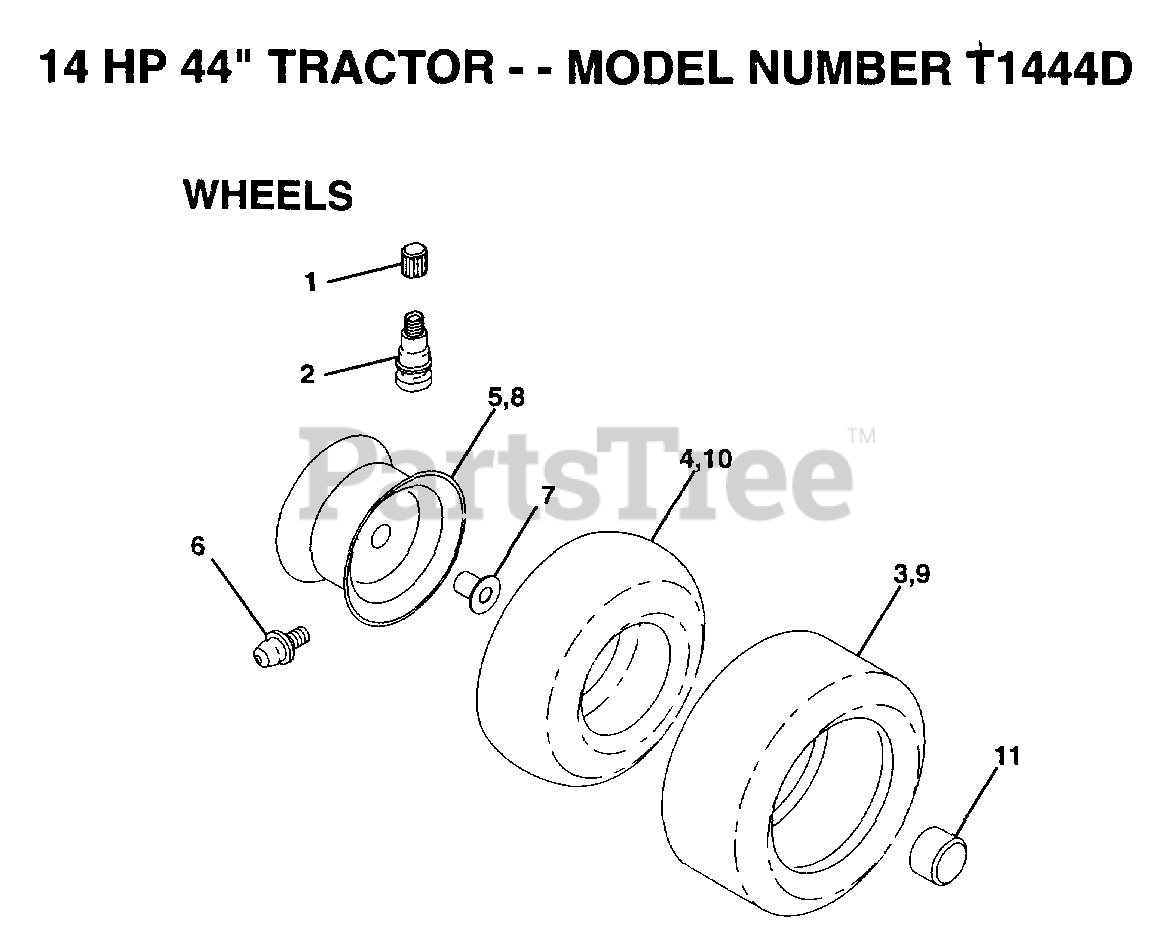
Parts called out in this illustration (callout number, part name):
1	VALVE CAP
2	VALVE STEM LT
4	TUBE.5.3/4.5/6
6	FITTING LT
7	"FLANGE, BEARING"
10	TUBE.18X9.5-8
11	HUB CAP
